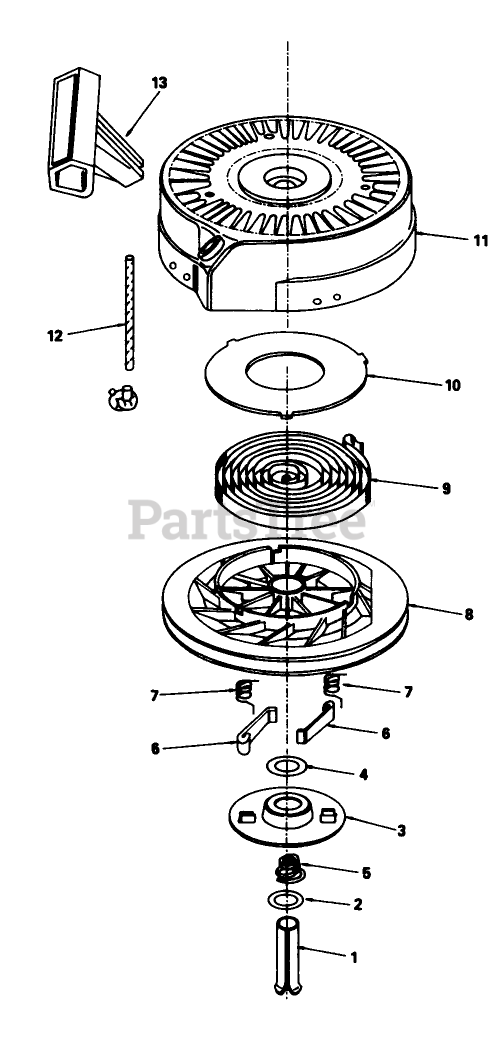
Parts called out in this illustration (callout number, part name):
1	Pin, Spring (Incl. Ref. #7)
2	Washer
3	Retainer
4	Washer
5	Brake Spring
6	Dog-Starter
7	Spring-Dog
8	Pulley
9	Rewind Spring
10	Cover-Spring
11	Housing-Starter
12	Rope-Starter (98 cut to length)
13	Handle-Starter
